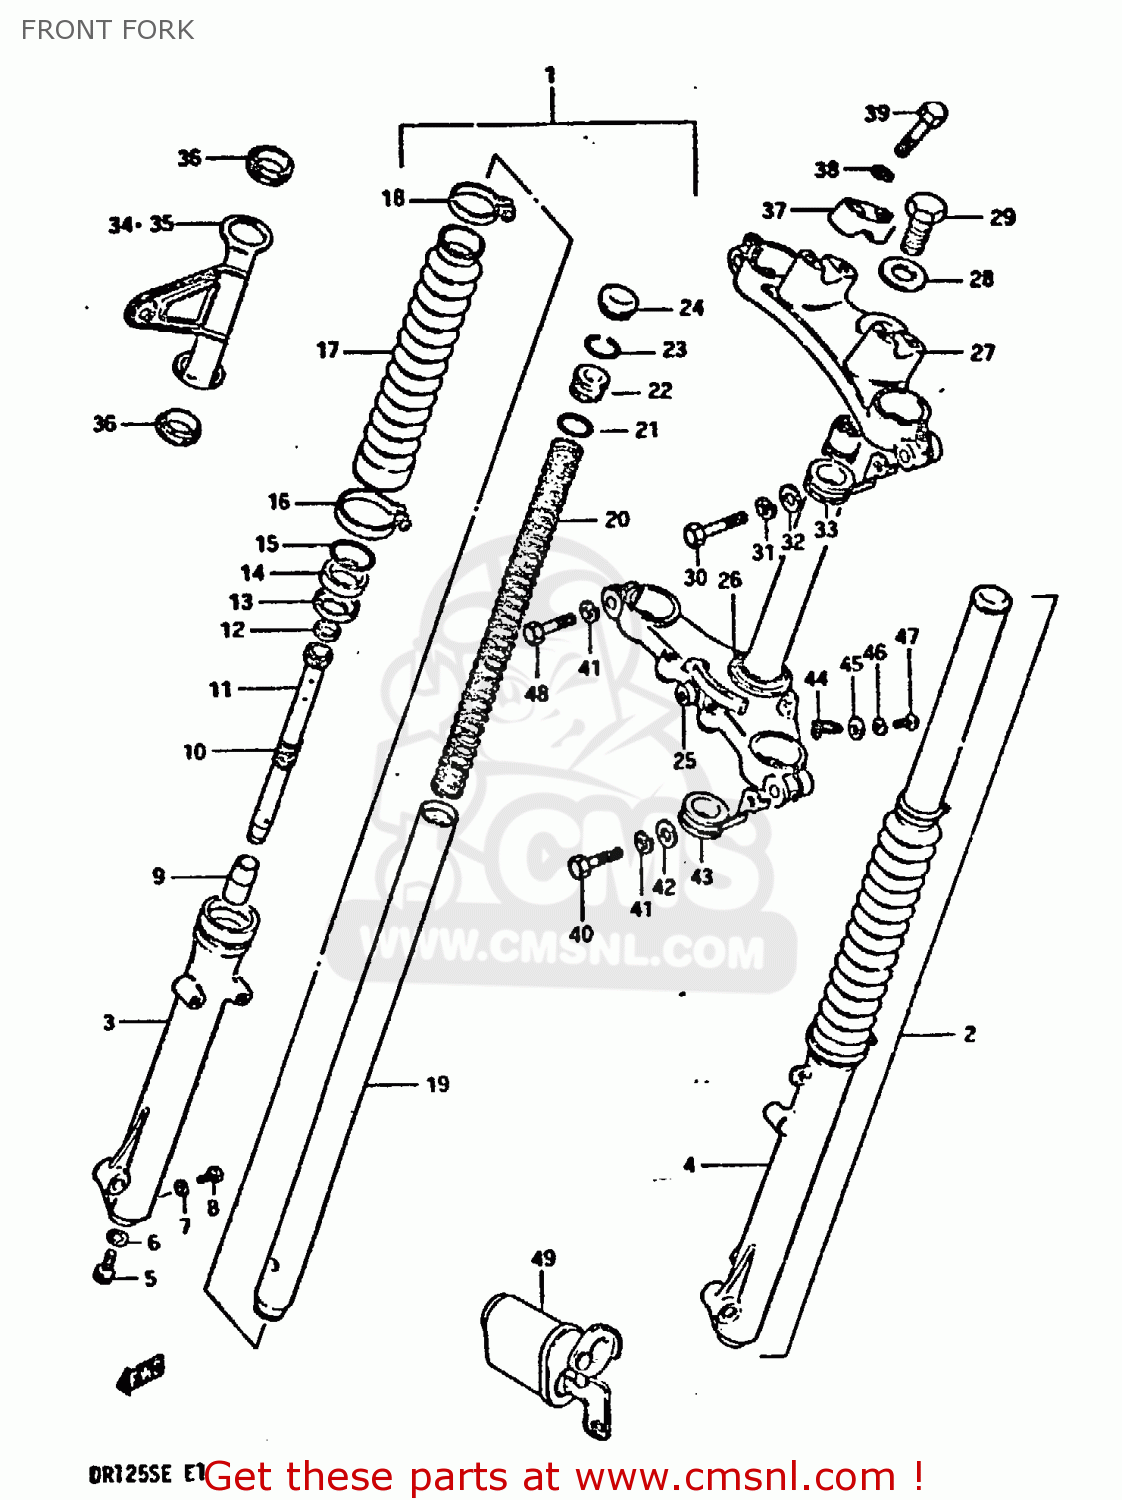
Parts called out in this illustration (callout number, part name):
1	DAMPER ASSY, RH (BLUE)
2	DAMPER ASSY, LH (BLUE)
3	TUBE,FORK,OUTER,RIGHT
4	TUBE,FORK,LEFT,OUTER
5	BOLT(8X27)
6	GASKET (NAS)
7	GASKET,DRAIN,PLUG (NAS)
8	BOLT
9	PIECE,OIL LOCK
10	SPRING,REBOUND
11	CYLINDER,FR FORK
12	RING,PISTON
13	SPACER
14	OIL SEAL,FRONT FORK
15	CIRCLIP,FORK OIL SEAL
16	BAND,FR FORK BOOT
17	BOOT(BLACK)
18	BAND,BOOT,UPPER
19	TUBE,FORK INNER
20	SPRING,FRONT FORK
21	O RING
22	SEAT,SPRING
23	RING,STOPPER
24	CAP
25	STEM,STEERING
26	RACE,STEERING OUTER LWR
27	HEAD, STEERING STEM (GOLD)
28	WASHER,STEM HEAD(10.5X30X3.2)
29	BOLT,FORK INNER TUBE
30	BOLT
31	LOCK WASHER
32	WASHER
33	GUIDE,CABLE
34	BRACKET,HEADLAMP,RIGHT
35	BRACKET,HEADLAMP,LEFT
36	CUSHION,HEADLAMP BRACKET
37	HOLDER,HANDLEBAR
38	LOCK WASHER
39	BOLT
40	BOLT 12X45
41	WASHER,LOCK 12
42	WASHER
43	GUIDE,CABLE
44	CLIP
45	WASHER
46	LOCK WASHER
47	SCREW 6X12
48	BOLT
49	LOCK ASSY, STEERING (NEIMAN TYPE EXECUTE
